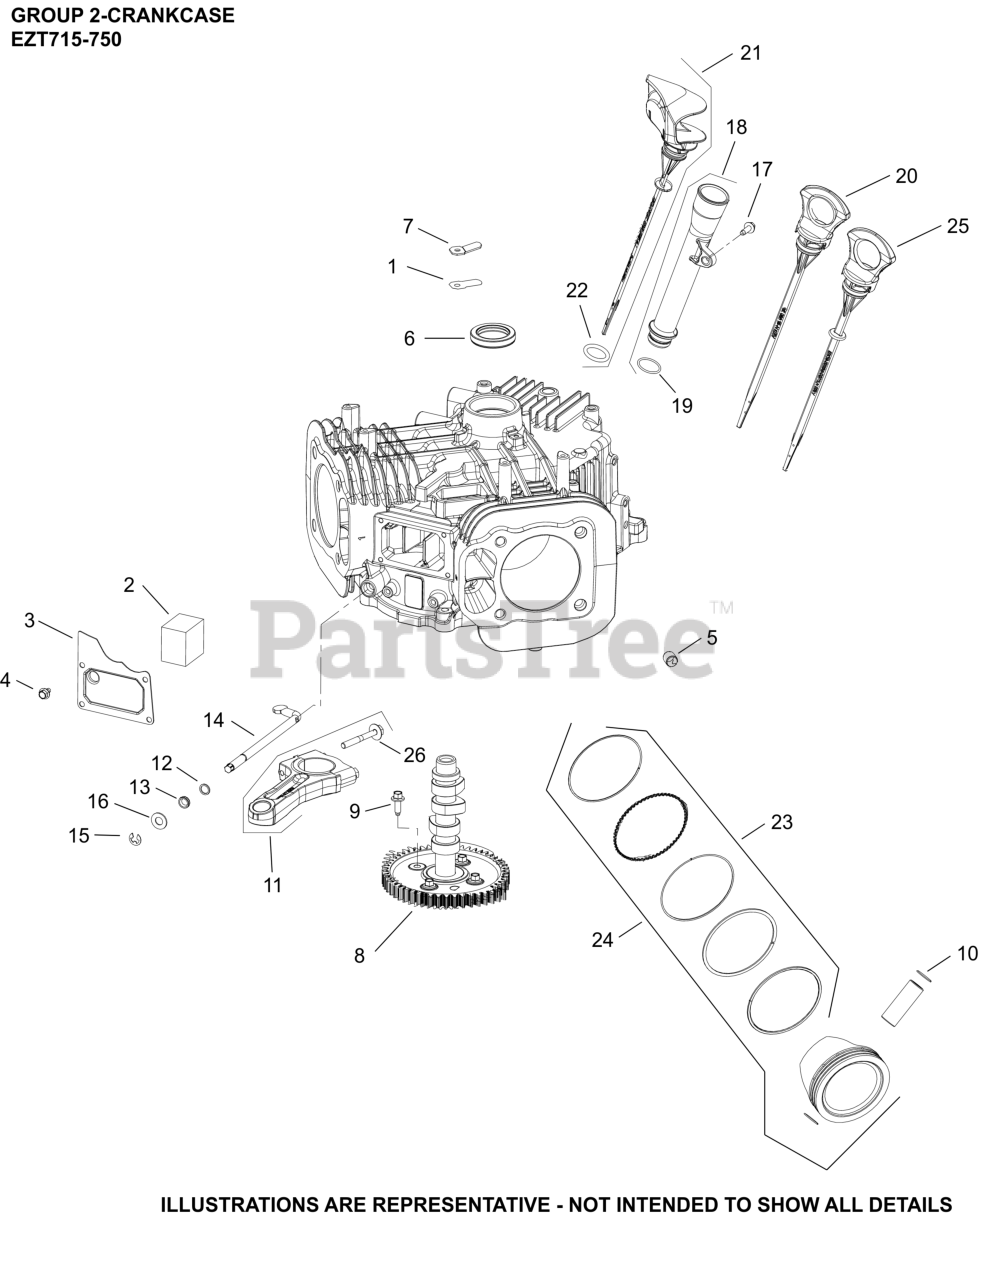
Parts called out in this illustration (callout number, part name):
1	REED, BREATHER
2	FILTER, BREATHER
3	COVER, BREATHER MEDIA
5	PIN, LOCATING
6	SEAL, OIL (HELIX LIP)
7	RETAINER, REED
8	CAMSHAFT ASSY
10	RETAINER, PISTON PIN
11	ROD, ASSEMBLY CONNECTING
12	WASHER, FLAT 11/32"
13	SEAL, GOVERNOR CROSS SHAFT
14	KIT, CROSS SHAFT
15	CLIP, RETAINER GOVERNOR SHAFT
16	WASHER, FLAT 9 MM
17	SCREW, THREAD FORMING
18	TUBE ASSEMBLY, OIL FILL
20	DIPSTICK, ASSY
24	KIT,PSTN/RNG STYLE B(STD)
